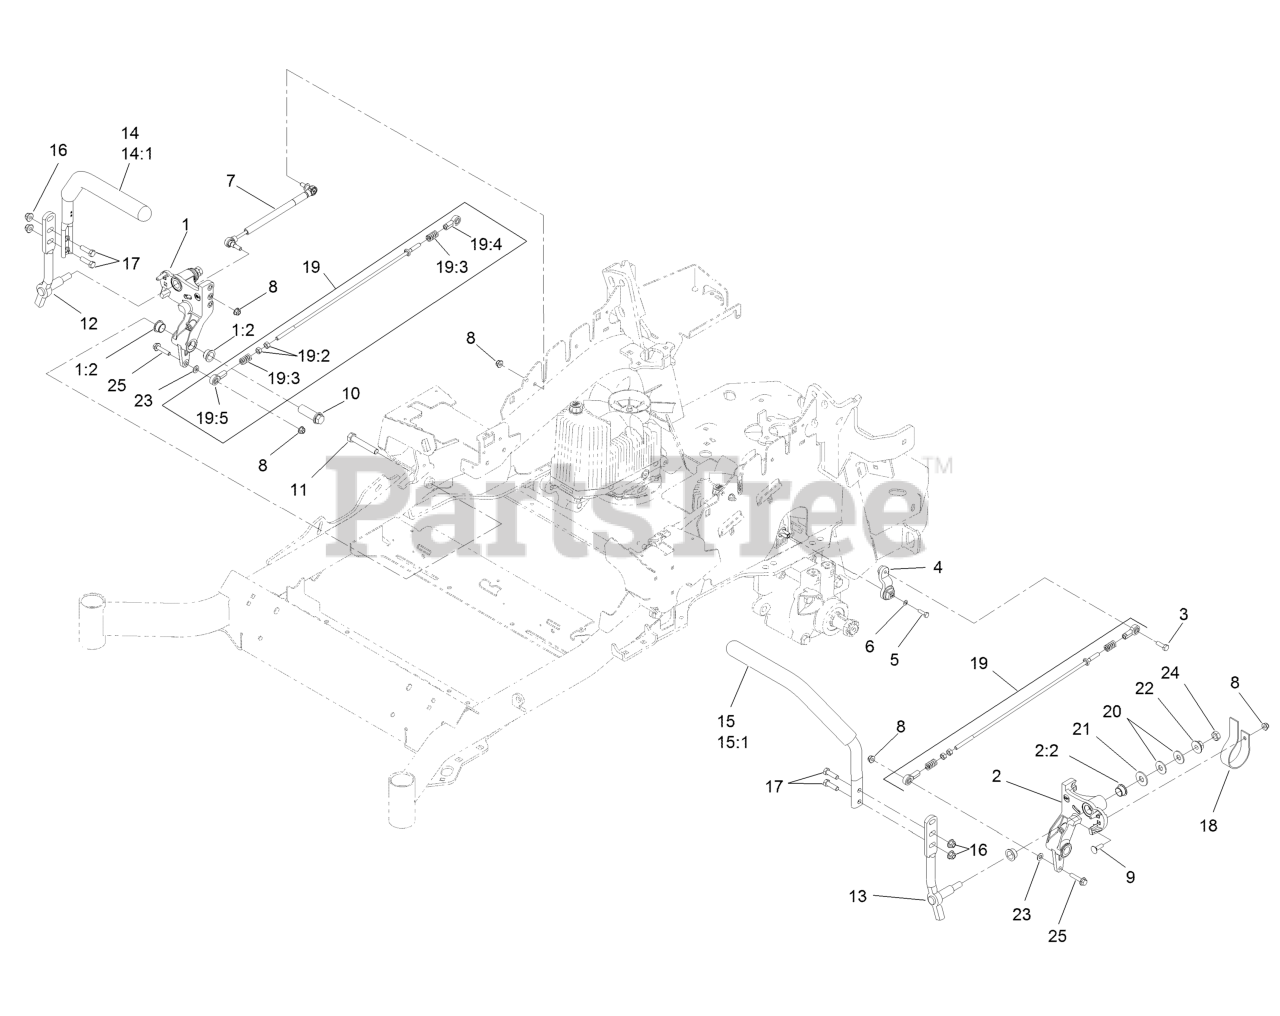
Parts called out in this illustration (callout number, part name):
1	RH Motion Control And Bushing ASM
1:2	Bushing-Flange
2	LH Motion Control And Bushing ASM
2:2	Bushing-Flange
3	Screw-HH, Thread Locking
4	Arm-Control, Pump
5	Screw-HH
6	Washer-Spring
7	Damper-Control, Motion
8	Nut-HF, NI
9	Bolt-CARR
10	Hub-Threaded
11	Screw-HH
12	Lever-Control Motion, RH
13	Lever-Control Motion, LH
14	RH Steering Handle ASM
14:1	Grip-Control, Lever
15	LH Steering Handle ASM
15:1	Grip-Control, Lever
16	Nut-HF, NI
17	Screw-HH
18	Spring-Leaf
19	Front Pump Linkage ASM
19:2	Nut-Hex
19:3	Spring-Compression
19:4	Balljoint-LH
19:5	Balljoint-RH
20	Washer-Spring
21	Washer-Flat
23	Washer-Plain
24	Nut-Jam
25	Screw-HHF
